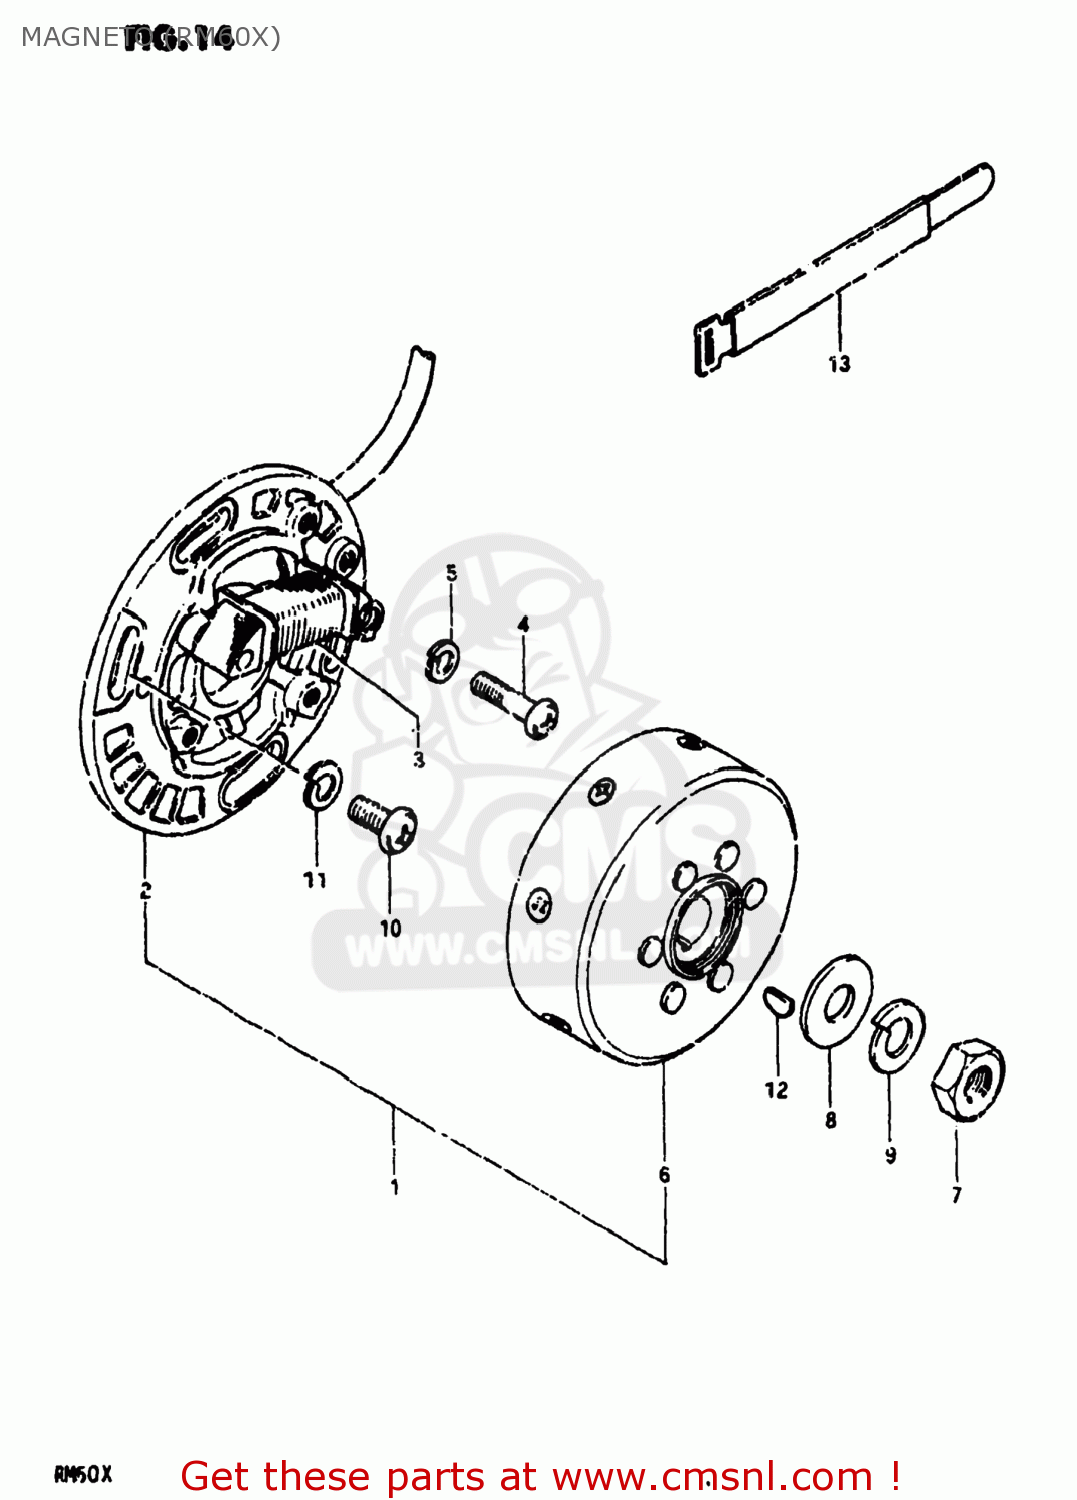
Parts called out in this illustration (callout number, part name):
1	MAGNETO ASSEMBLY
2	STATOR ASSEMBLY
3	COIL,PRIMARY
4	SCREW
5	LOCK WASHER
6	ROTOR ASSEMBLY
7	NUT (10MM)
8	WASHER
9	LOCK WASHER
10	SCREW
11	WASHER
12	KEY
13	CLAMP
